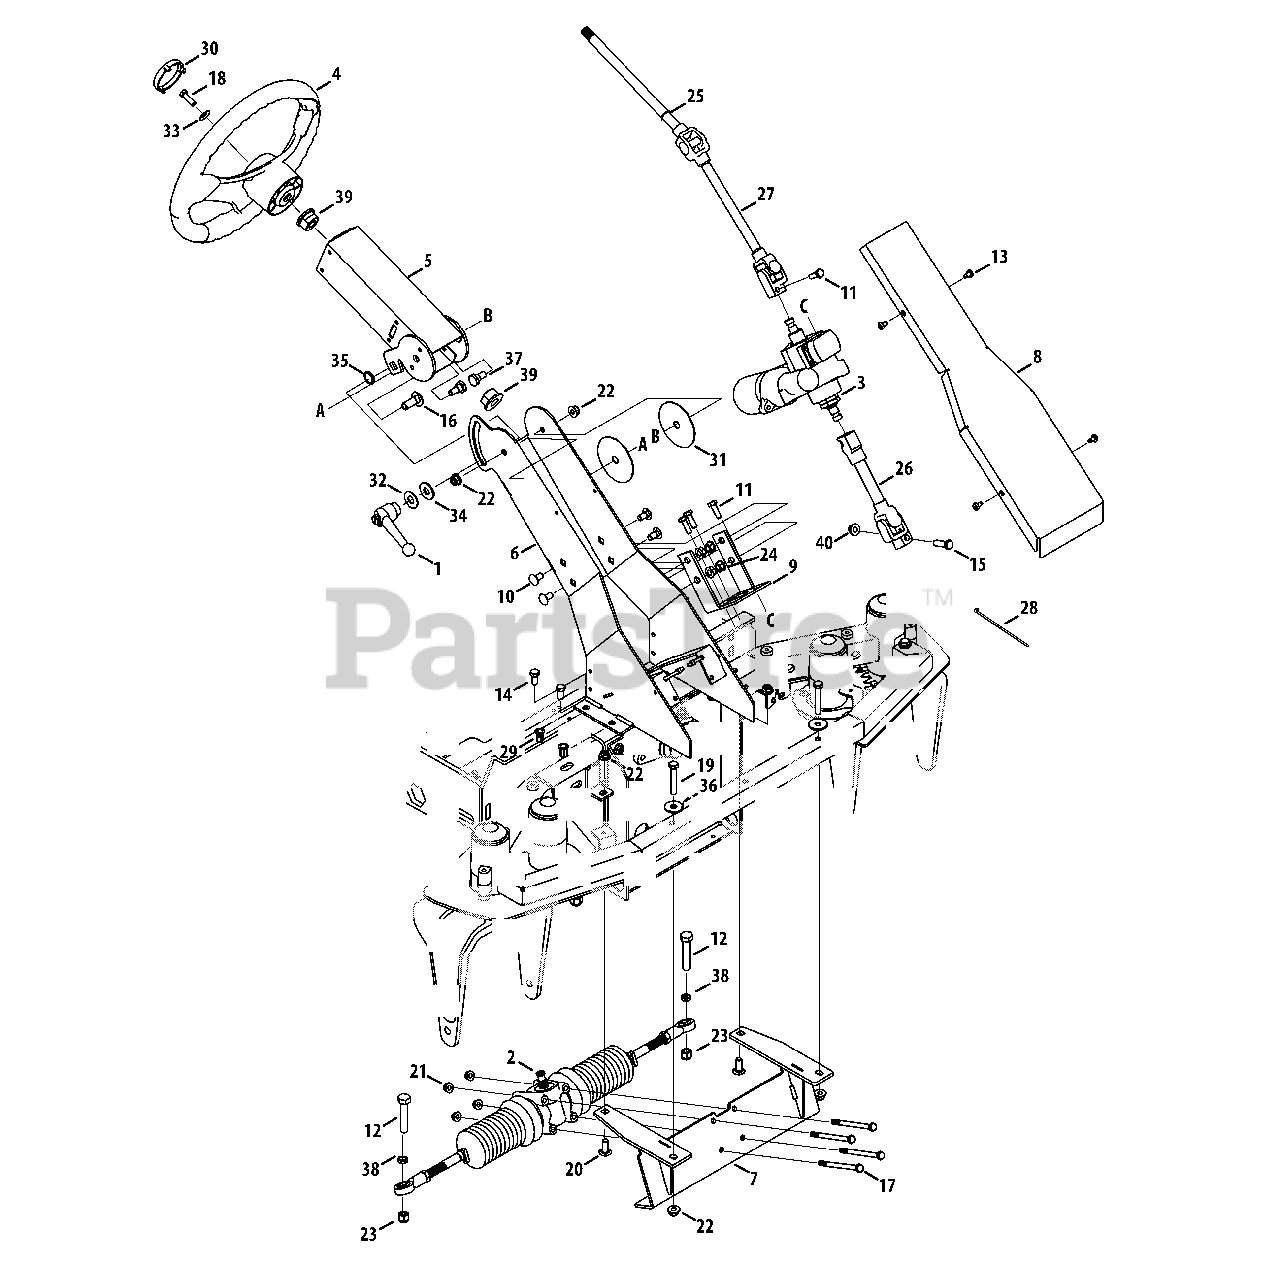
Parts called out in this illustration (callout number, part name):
1	Steering Column Adjustment Lever
2	Steering Gearbox
3	Power Steering Arm
3	Module, EPS Control
4	Steering Wheel
5	Upper Column
6	Base Column
7	Steering Rack Mount
8	Front Column Cover
9	Power Steering Mount
10	Carriage Bolt, 3/8-16 x .750
11	Hex Cap Screw, M8-1.25 x 25.0
12	Hex Cap Screw, 1/2-20 x 2.25
13	Screw, 1/4-20 x .500
14	Hex Cap Screw, 3/8-16 x 1.00
15	Hex Cap Screw, 3/8-16 x 1.50
16	Carriage Bolt, 1/2-13 x 1.25
17	Hex Cap Screw, 5/16-18 x 4.00
18	Hex Cap Screw, 5/16-18 x 1.00
19	Hex Cap Screw, 3/8-16 x 2.50
20	Carriage Bolt, 3/8-16 x 1.00
21	Nut, 5/16-18, Flangelock
22	Nut, 3/8-16, Flnagelock
23	Nut, 1/2-20, Hexlock
24	Nut, 3/8-16, Flangelock
25	Retainer Ring, .625
26	Steering Shaft, Bottom
27	Steering Shaft, Top
28	Cable Tie
29	Rivet, 3/8-16
30	Cap, No Sprig
31	Column Wear Plate
32	Washer, .531 x 1.25 x .100
33	Bevel Washer, .340 x .872 x .060
34	Washer, .640 x 1.25 x .050
35	Lock Washer, 17 x 23.8 x 1.95
36	Washer, .406 x 1.00 x .105
37	Shoulder Bolt, .496 x .336, 3/8-16
38	Spacer, .515 x .75 x .220
39	Flange Bearing, .63 x 1.15
40	Nut, Hex Lock, 3/8-16
